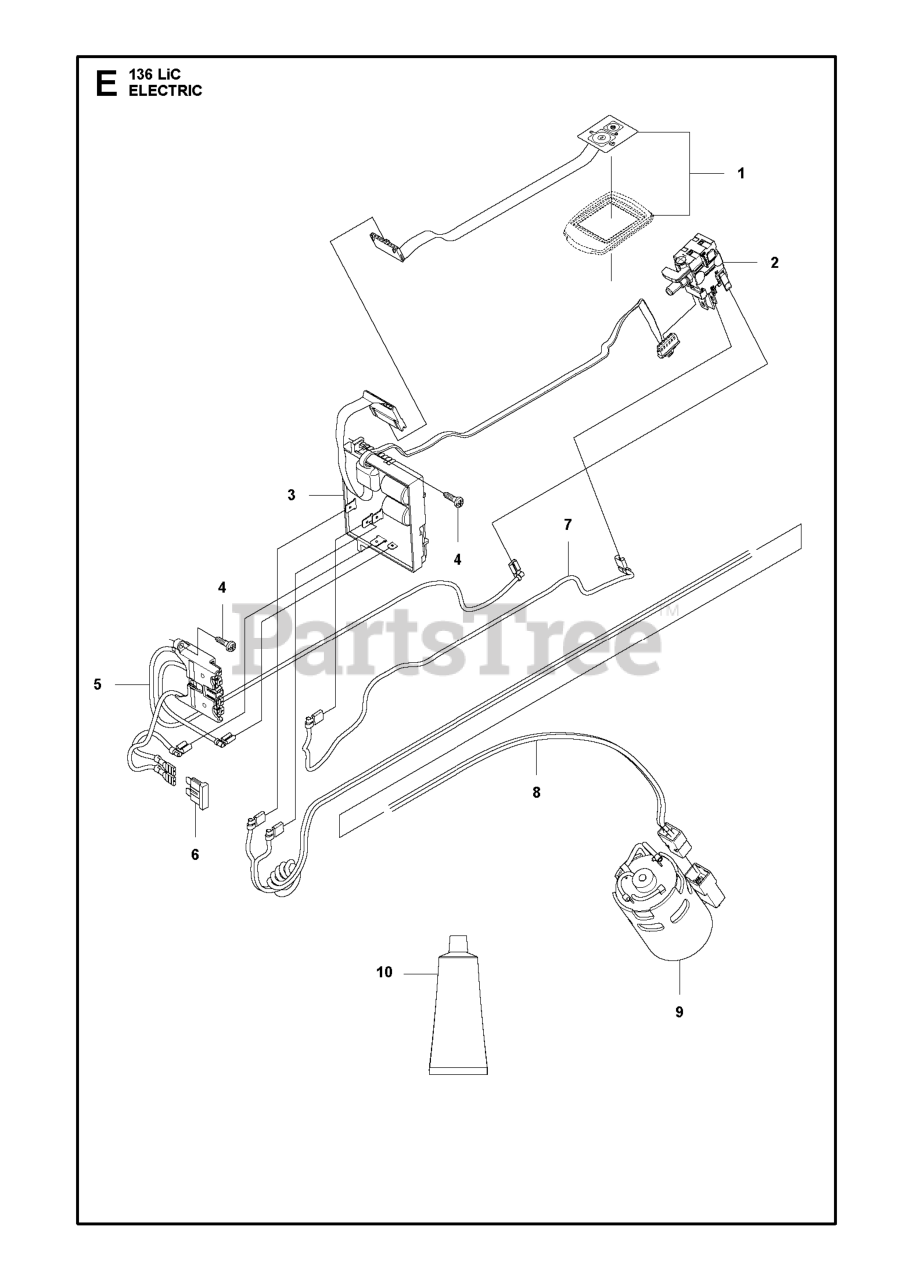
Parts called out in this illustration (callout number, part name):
2	TRIGGER SWITCH
3	DC MOTOR CONTROLLER ASSY
5	WIRING ASSY
7	WIRING ASSY
8	WIRING ASSY
9	MOTOR
10	GREASE TUBE Q8 RUYSDAEL WR2
